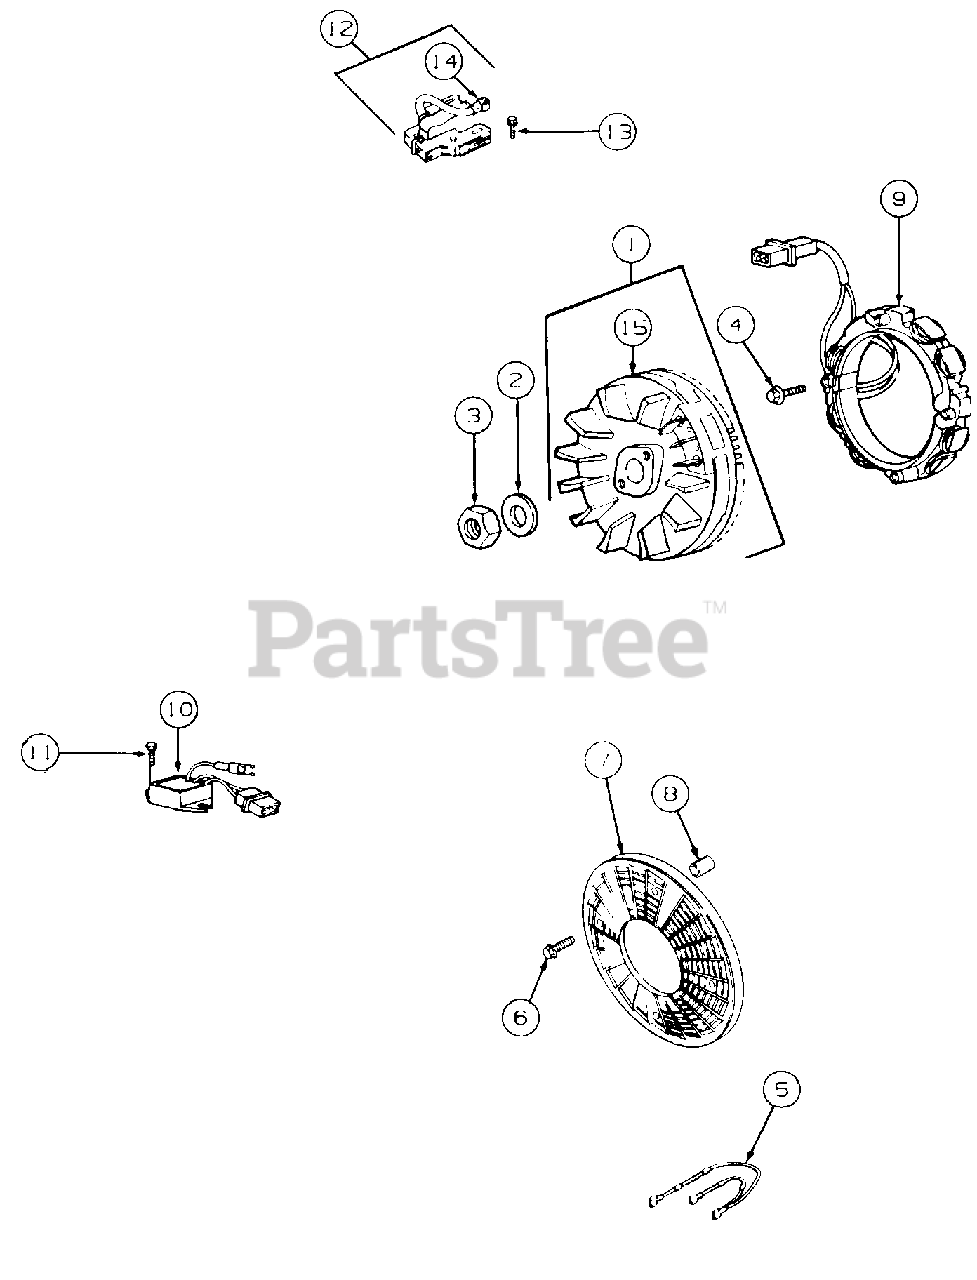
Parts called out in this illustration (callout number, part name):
1	Flywheel & Ring Gear
2	Washer, Spring
4	Screw, Mounting
5	Wire, Ground
6	Screw, Sems
7	Screen, Rotating
8	Spacer
9	Stator, 16 Amp
10	Regulator
11	Screw, Mounting
12	Armature
13	Screw, Mounting
14	Terminal
15	Gear, Flywheel Ring
